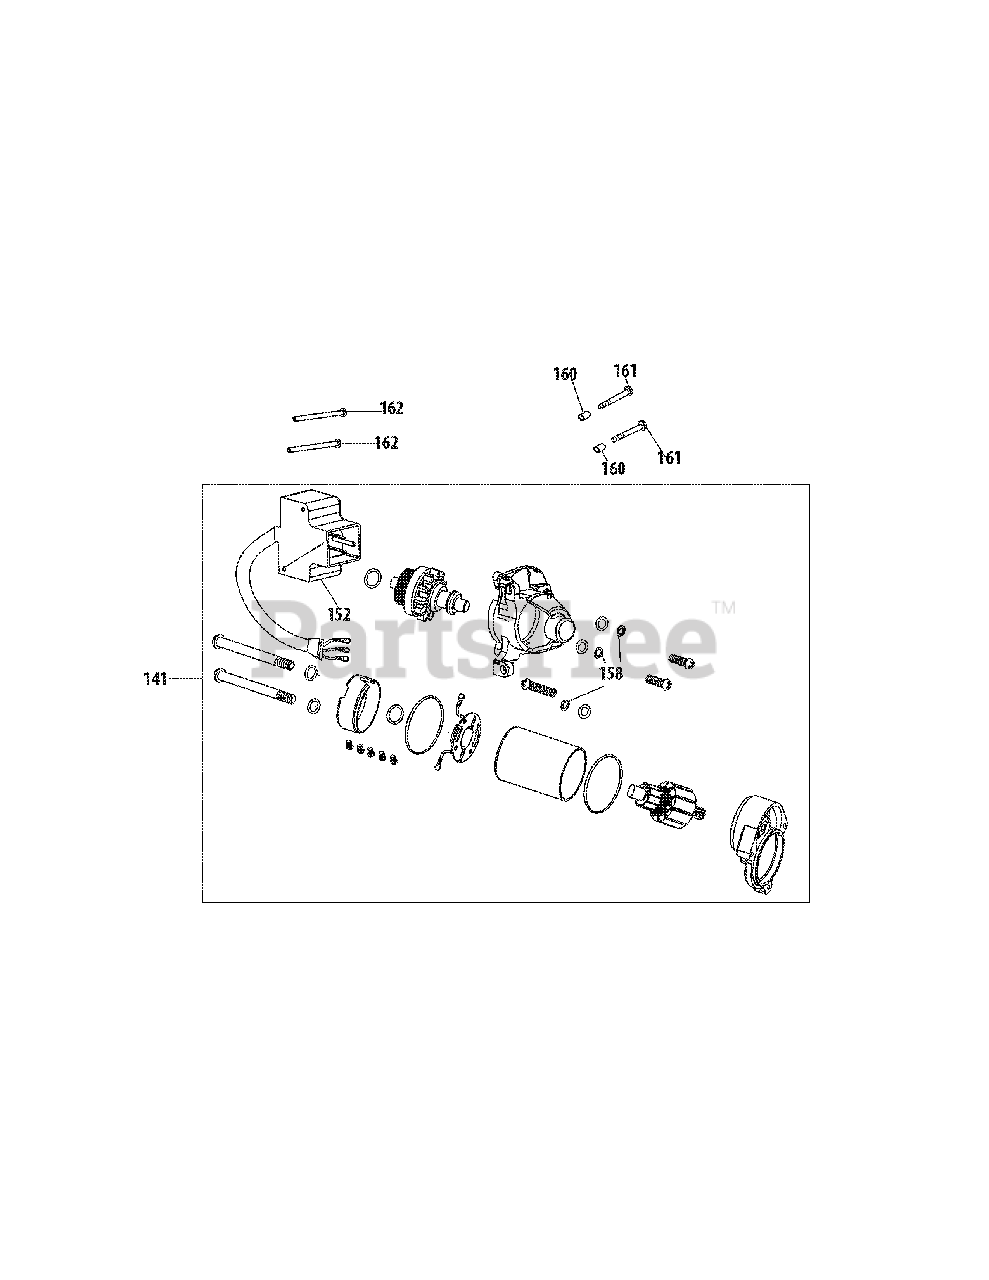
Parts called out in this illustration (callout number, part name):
141	ELECTRIC STARTER
152	MAIN CABLE
158	SPRING WASHER F5
160	DOWEL PIN F8×8
161	BOLT M6×32
162	BOLT M4×55
